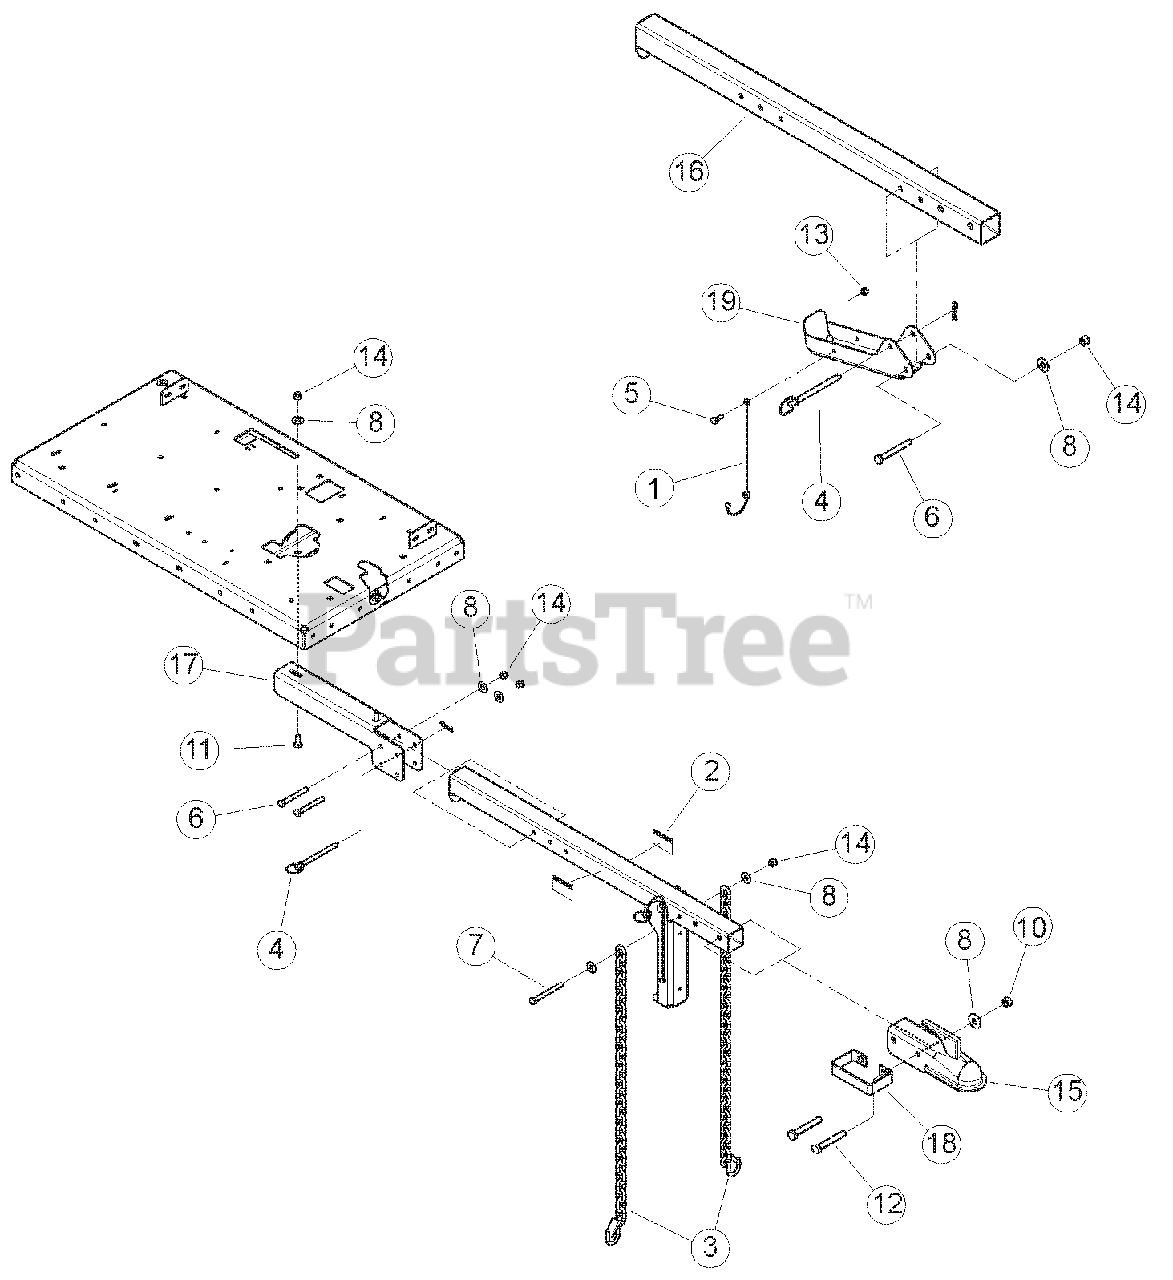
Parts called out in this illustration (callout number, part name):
1	LANYARD, NYLON
2	REFLECTOR, WIDE ANGLE AMBER
3	CHAIN, SAFETY 5000 LB W/LATCH
4	PIN, 3/8 HITCH
5	BOLT, 1/4 X 3/4 HEX HD GR5ZP
6	BOLT, 3/8 X 3 HEX HD GR5 ZP
7	BOLT, 3/8 X 3-1/2 HEX HD GR5 ZP
8	WASHER, 3/8 FLAT ZP
9	WASHER, 1/2 FLAT ZP
10	NUT, 1/2 CENTERLOCK GRB ZP
11	BOLT, 3/8 X 1 CRG GR5 NC ZP
12	BOLT, 1/2 X 3-1/4 HCS GR5 ZP
13	NUT, 1/4 NE NYLOCK ZP
14	NUT, 3/8 NE NYLOCK ZP
15	TRAILER HITCH COUPLER
16	WELDMENT, HITCH POLE
17	CHANNEL, HITCH POLE
18	HANDLE, COUPLER
19	STAND, JACK
